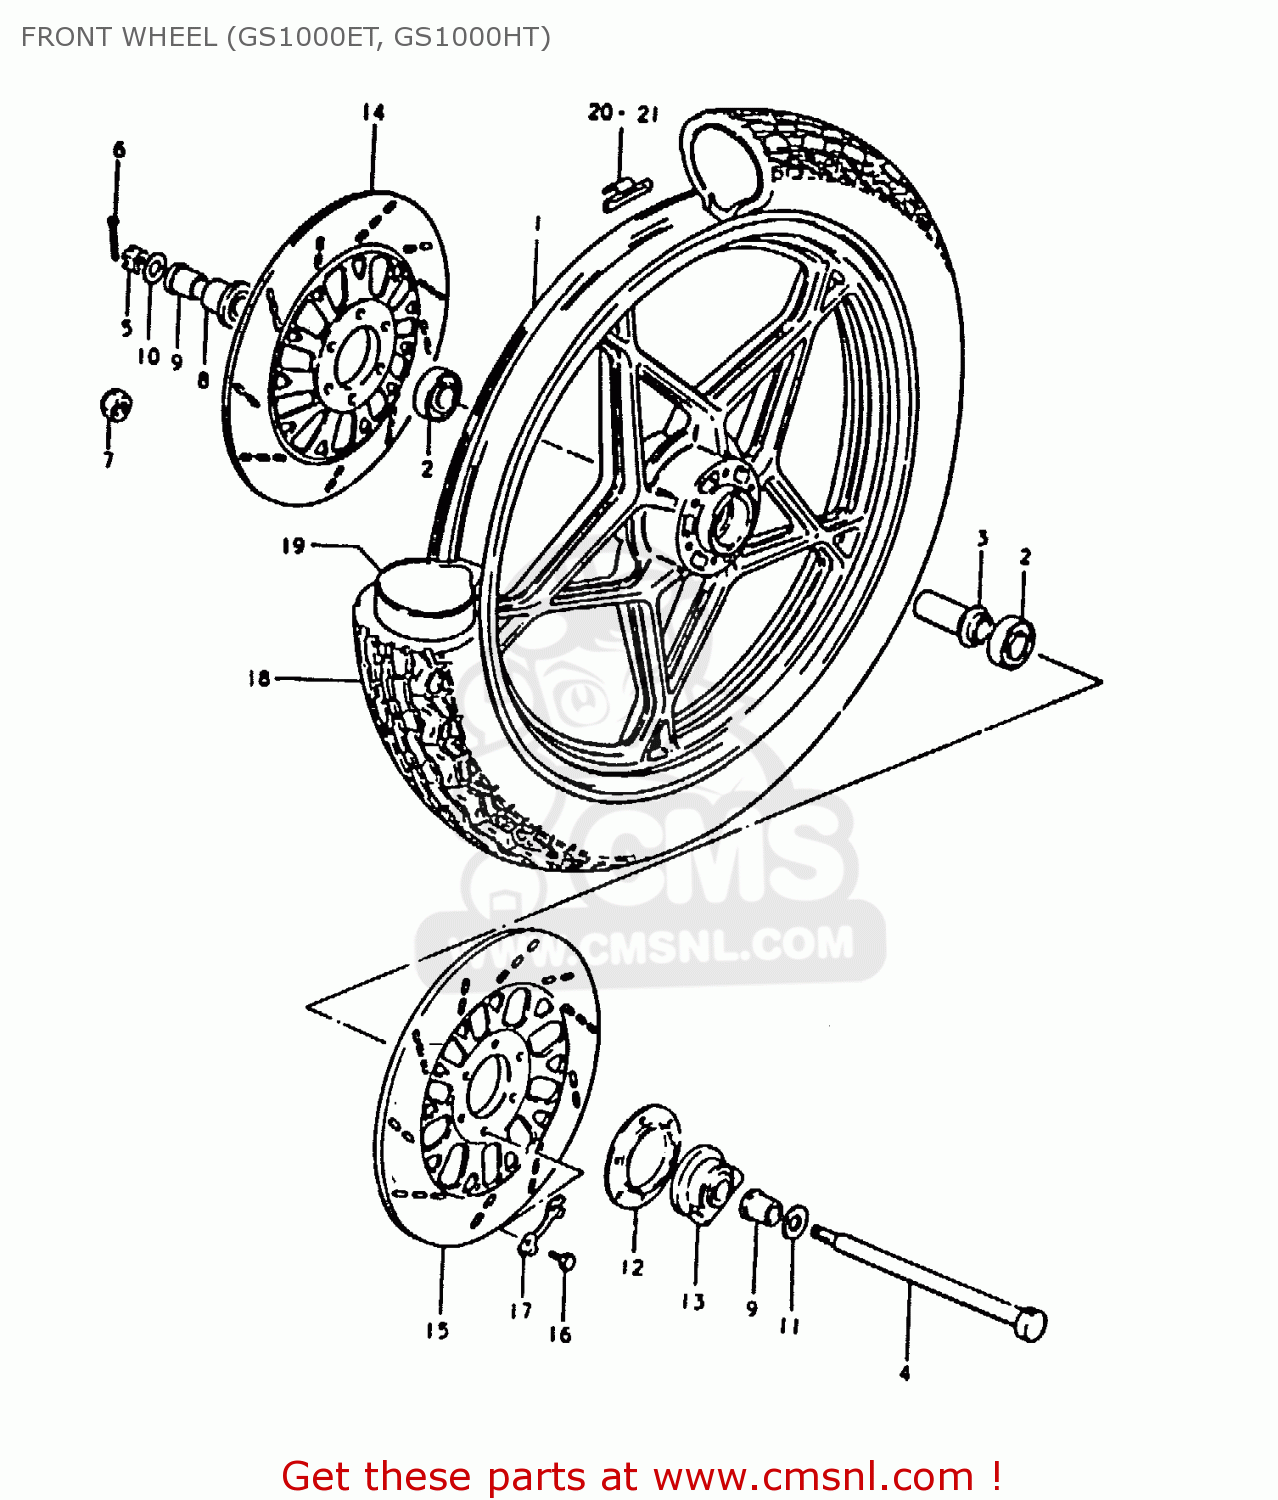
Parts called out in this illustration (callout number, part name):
1	WHEEL, FRONT
2	BEARING
3	SPACER,FR HUB BEARING
4	AXLE,FR
5	NUT 12MM
6	COTTER PIN
8	SPACER,FR AXLE,R
9	SPACER,FR AXLE,L
10	WASHER
11	WASHER
12	DUST SEAL,SPEEDOMETER GEAR BOX
13	BOX ASSEMBLY,SPEEDOMETER GEAR
14	DISC,FR BRAKE,R
15	DISC,FR BRAKE,L
16	BOLT(8X25)
17	WASHER
18	TIRE,FRONT
19	TUBE,INNER
20	BALANCER,WHEEL
21	BALANCER,WHEEL
